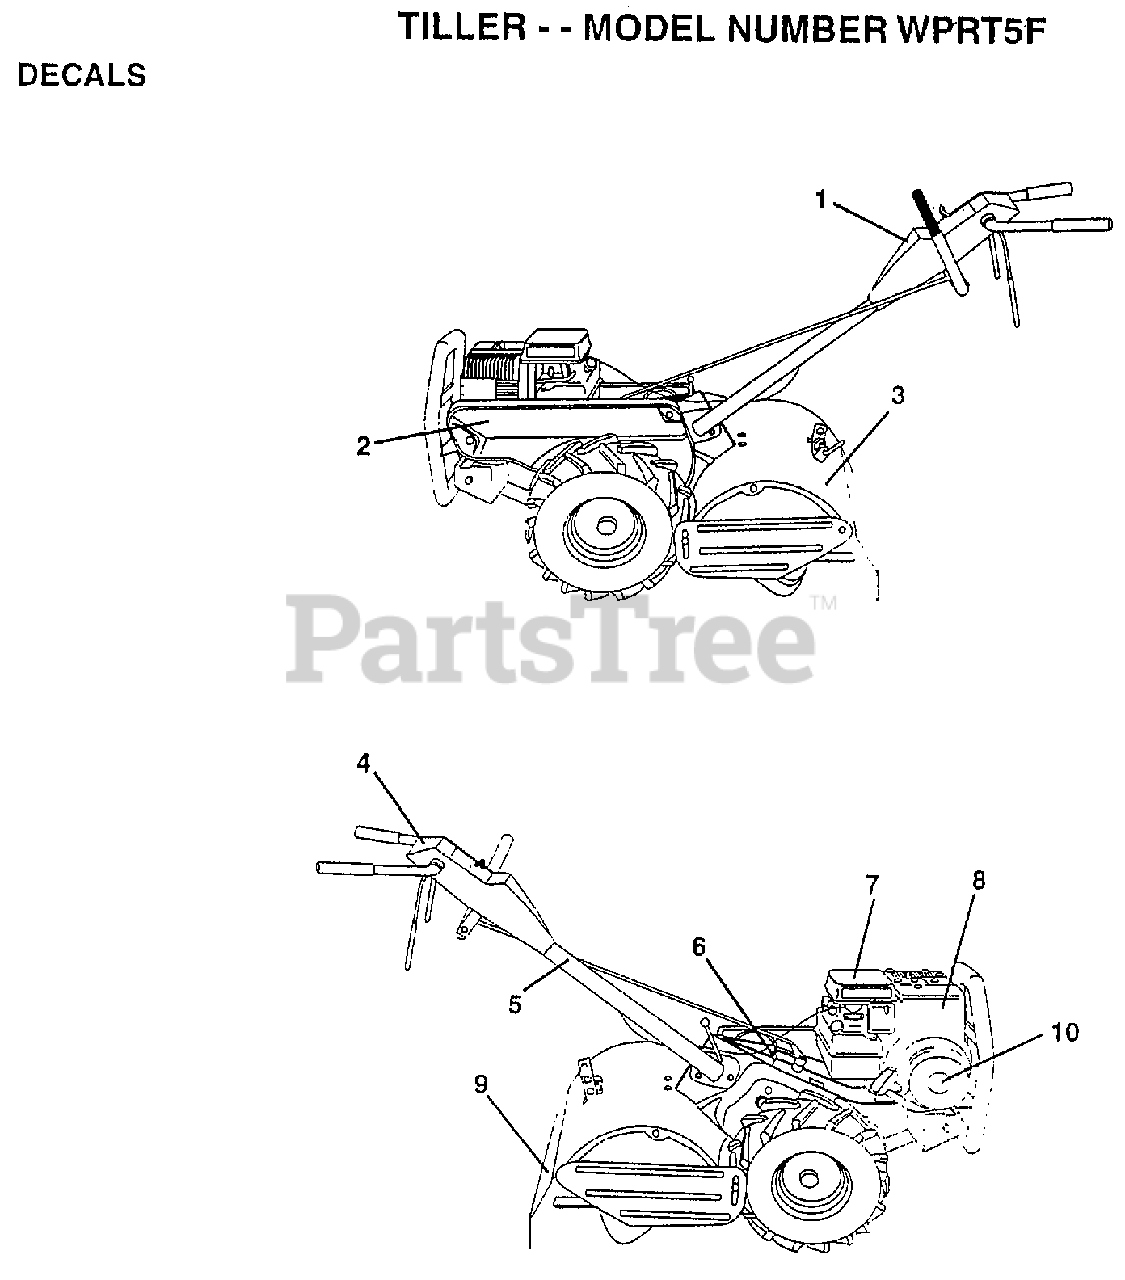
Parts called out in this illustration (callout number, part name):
1	DECAL.PNL.CONTROL
2	DECAL.GD.BELT.5HP
3	DECAL.SHLD.TINE
4	DECAL.INSTRUCTION
5	DECAL TI
6	DECAL CRT
8	DECAL, BRIGGS & STRATTON
9	DECAL TI
10	DECAL, 5 HP
